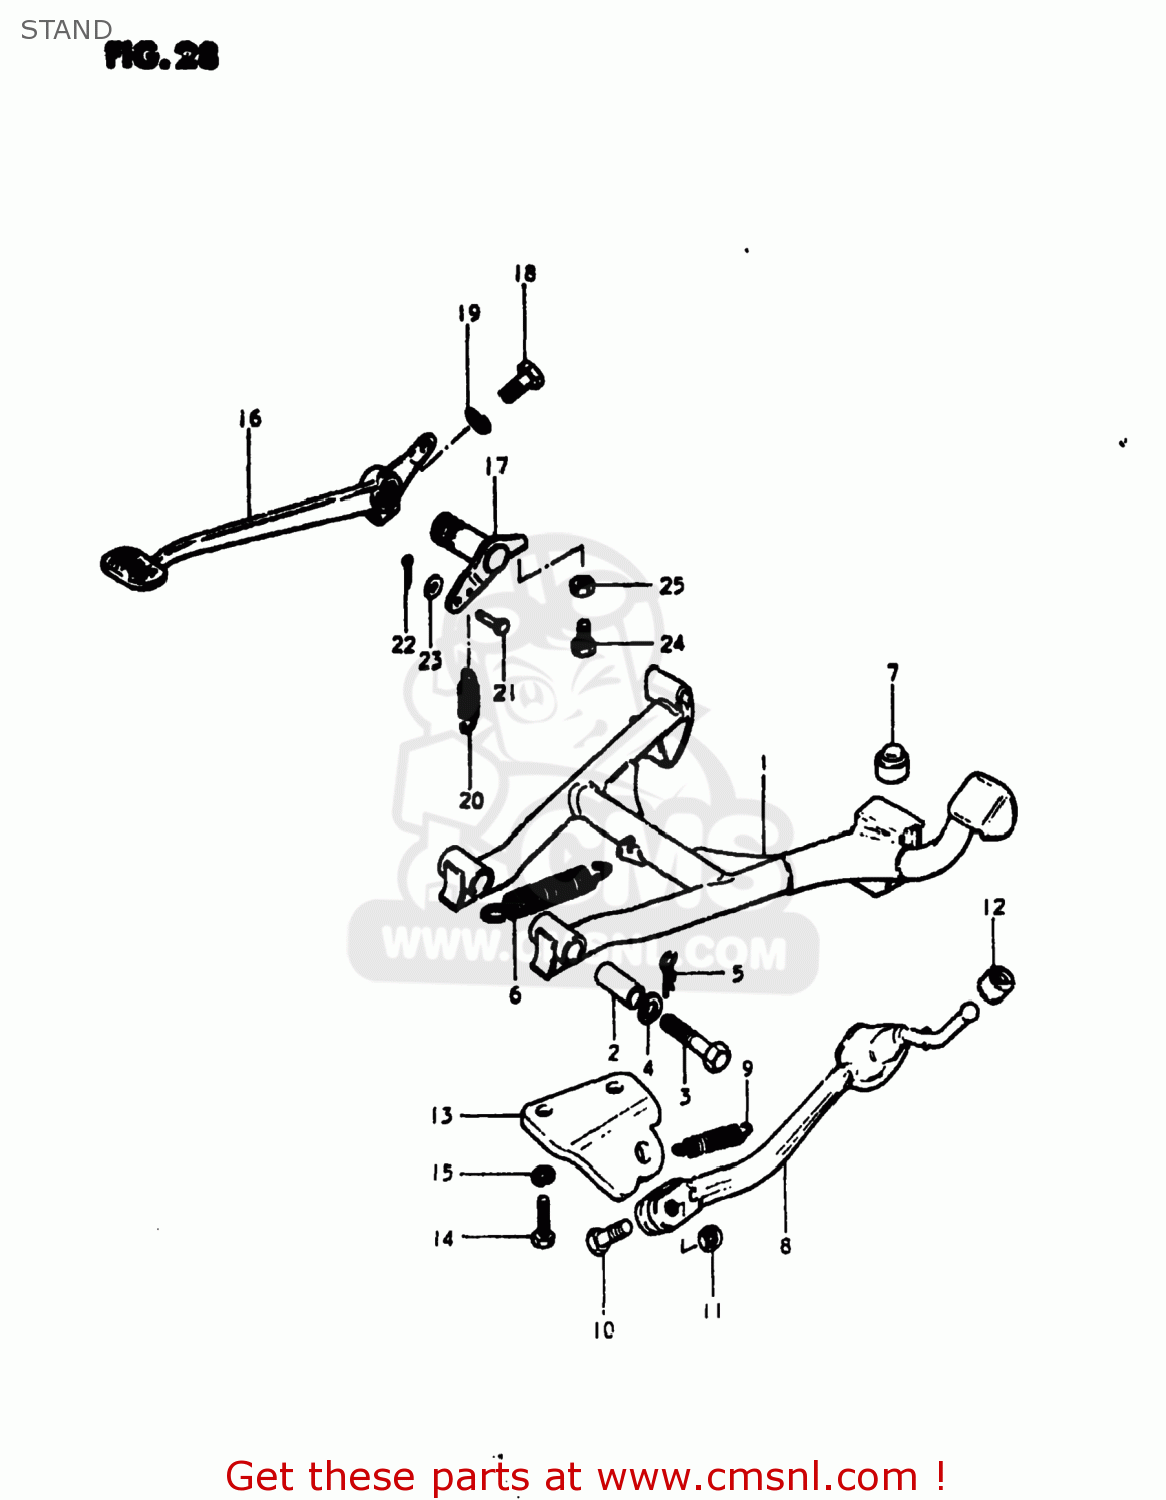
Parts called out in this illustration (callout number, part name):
1	STAND,CENTER
2	SPACER(10X16X38.8)
3	BOLT
4	LOCK WASHER
5	CLIP
6	SPRING
7	CUSHION
8	STAND,SIDE
9	SPRING
10	BOLT(10X30)
11	NUT
12	CUSHION
13	BRACKET,SIDE STAND
14	BOLT
15	LOCK WASHER
16	PEDAL,BRAKE
17	ARM,BRAKE PEDAL
18	BOLT
19	LOCK WASHER
20	SPRING
21	PIN
22	PIN
23	WASHER
24	BOLT
25	NUT
